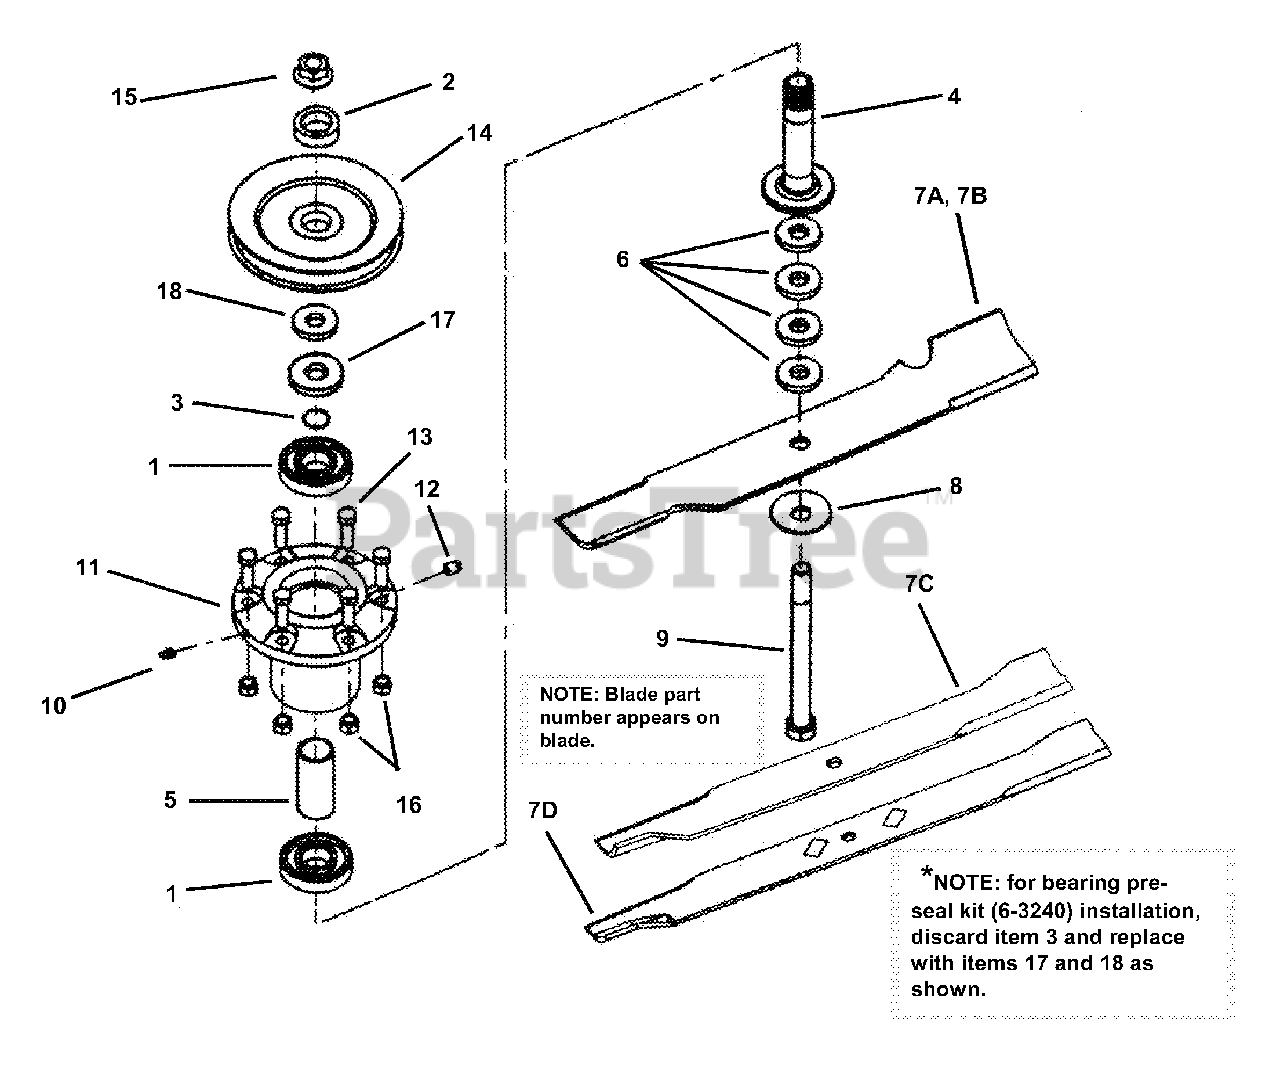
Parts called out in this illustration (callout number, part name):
1	BEARING, Sealed
2	WASHER, Spindle
3	SNAP-RING, Spindle Shaft
4	SHAFT, Spindle
5	SPACER, Bearing
6	SPACER, Blade
7A	BLADE, 21" (61" Deck) (High Lift)
7B	BLADE, 18" (52" Deck) (Low Lift)
7C	BLADE, 21" (61" Deck) (Low Lift)
7D	BLADE, 25" (73" Deck)
8	WASHER, Beveled
9	BOLT, 5/8-11 x 7-1/2" Hex Head Cap, Grade 5
10	LUBE FITTING, 1/4-28 Thread Forming
11	HOUSING, Cutter
12	VENT, Spindle
13	BOLT, 3/8-16 x 1-1/4" Rib Necked
14	PULLEY, 5-3/4" O.D. (61" Deck)
15	NUT, 5/8-18 Hex Flange Lock, Grade 5
16	NUT, 3/8-16 HEX NYLON LOCK
17	SEAL, Nylos
18	WASHER
